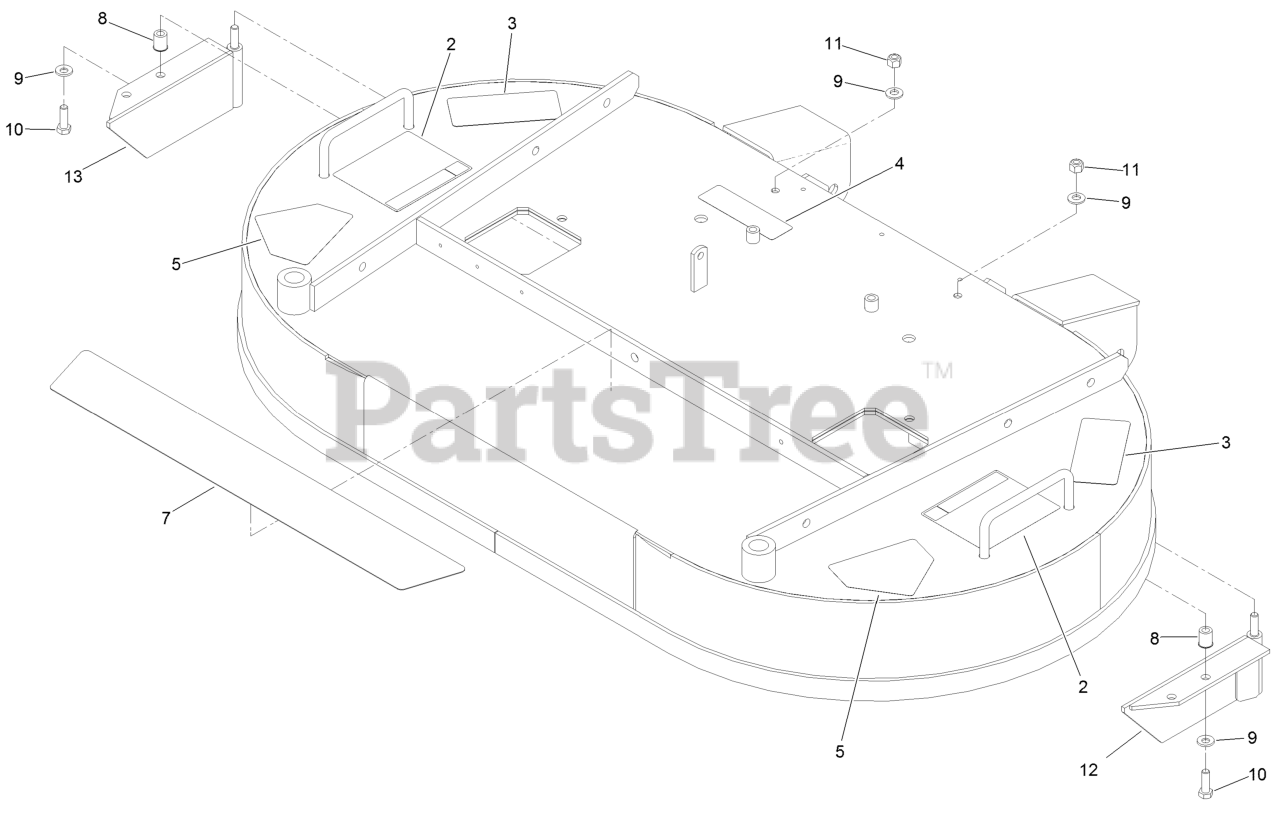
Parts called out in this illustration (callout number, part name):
2	DECAL-HEIGHT ADJUST, CUTT
3	DECAL-TORQUE, BLADE BOLT
4	DECAL-COVER, MISSING
5	DECAL-DANGER
7	PAD-SKID, ANTI
8	NUT-CLINCH
9	WASHER-SPRING
10	SCREW-HH
11	NUT-LOCK, NI
12	BAFFLE-LH
13	BAFFLE-RH
